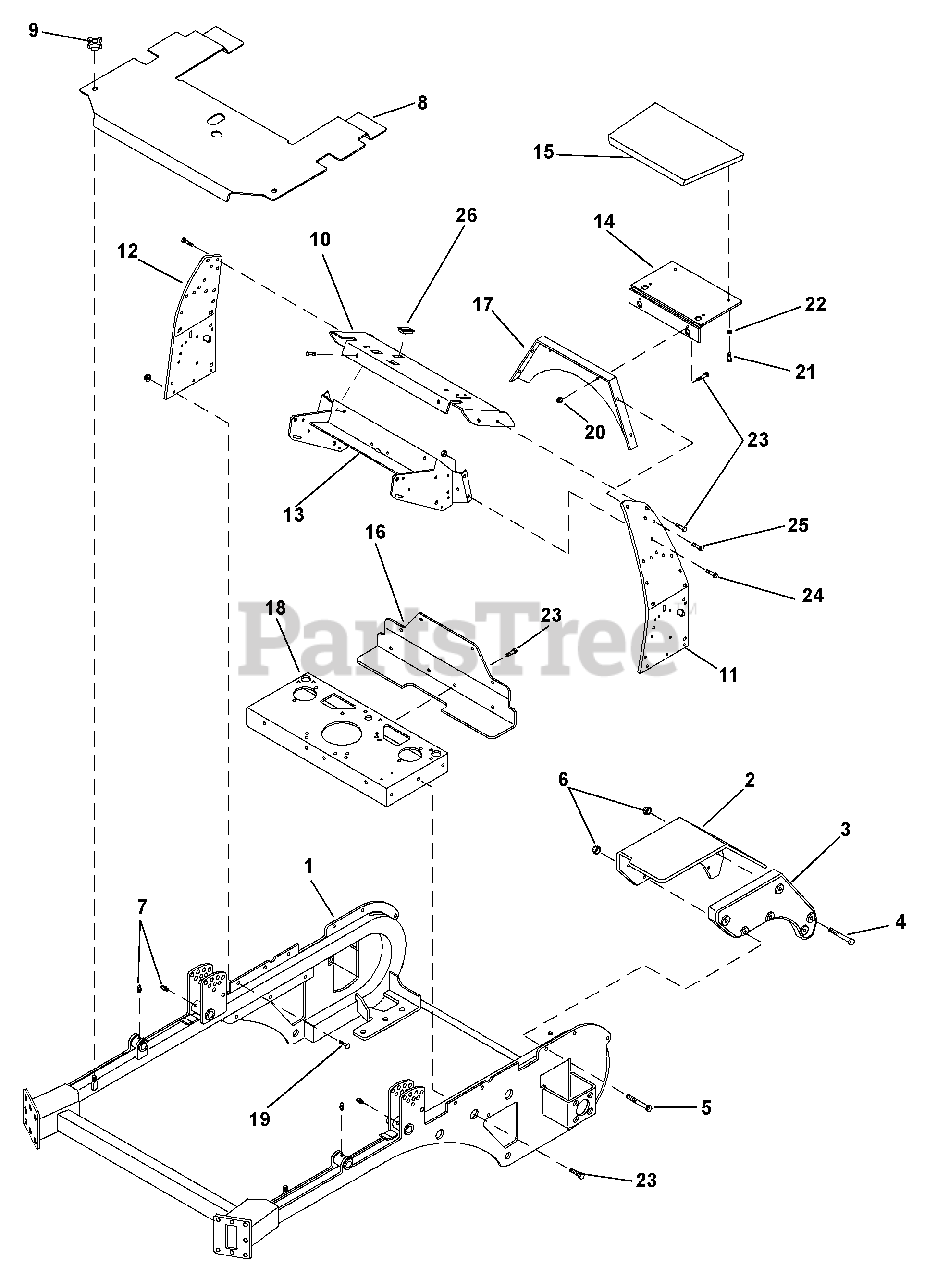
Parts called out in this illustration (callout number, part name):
1	Frame
2	Fender, Left
3	Weight
4	Bolt, Hex M8 x 1.25 x 65
5	Bolt, Hex, M8 x 1.25 x 70
6	Nut, Locking, Nylon M8-1.25
7	Lubrication Fitting
8	Deck Shield Assembly (994100)
9	Knob, 3/8-16 Insert
10	Control Console
11	Side Bracket, Left
12	Side Bracket, Right
13	Handle Mount
14	Plate, Thigh Pad
15	Thigh Pad
16	Shield
17	Plate
18	Engine/Traction Deck
19	Carriage Bolt, M10 x 1.5 x 25
20	Nut, Locking, Nylon M10-1.5
21	Bolt, Hex, .25-20 x .75
22	Washer, Lock .25 x .062
23	Bolt, Hex, 10 x 1.5 x 20
24	Bolt, Hex, 10 x 1.5 x 25
25	Bolt, Hex, .38-16 x .75
26	Plug, Euro Style, Optional Lights
